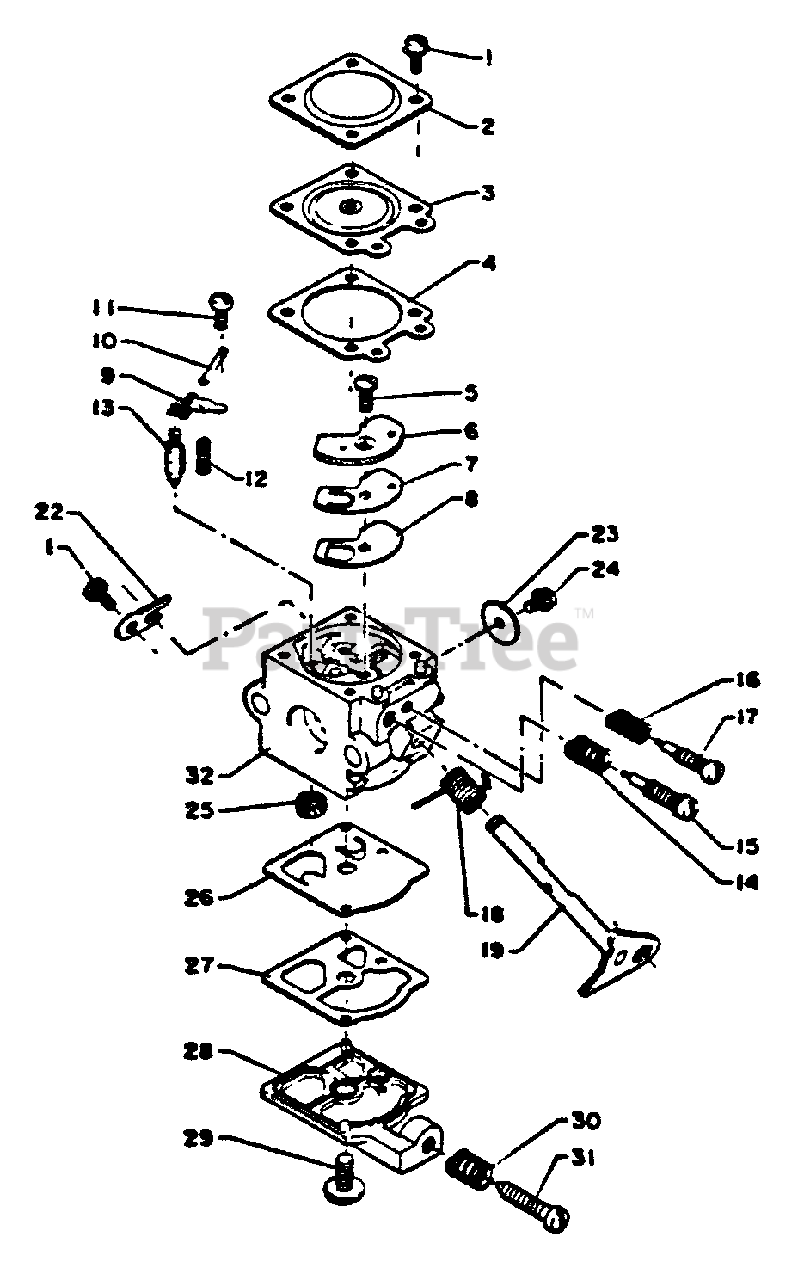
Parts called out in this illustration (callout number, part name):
1	SCREW
2	COVER, METERING
3	DIAPHRAGM, METERING
4	GASKET, METERING
5	SCREW, CIRCUIT PLATE
6	PLATE, CIRCUIT
7	DIAPHRAGM, CIRCUIT PLATE
8	GASKET, CIRCUIT PLATE
9	LEVER, METERING
10	PIN, METERING LEVER
11	SCREW, METERING LEVER PIN
12	SPRING, METERING LEVER
13	VALVE, INLET NEEDLE
14	SPRING, HIGH SPEED NEEDLE
15	NEEDLE - HIGH SPEED
16	SPRING, IDLE ADJUST
17	NEEDLE - LOW SPEED
18	SPRING, THROTTLE RETURN
19	SHAFT, THROTTLE
22	CLIP, THROTTLE SHAFT
23	VALVE, THROTTLE
25	STRAINER
26	DIAPHRAGM, PURGE
27	GASKET, PURGE
28	COVER, PUMP
29	SCREW, PUMP COVER
30	SPRING, IDLE ADJUST
31	SCREW, IDLE ADJUST
32	BODY, CARBURETOR
